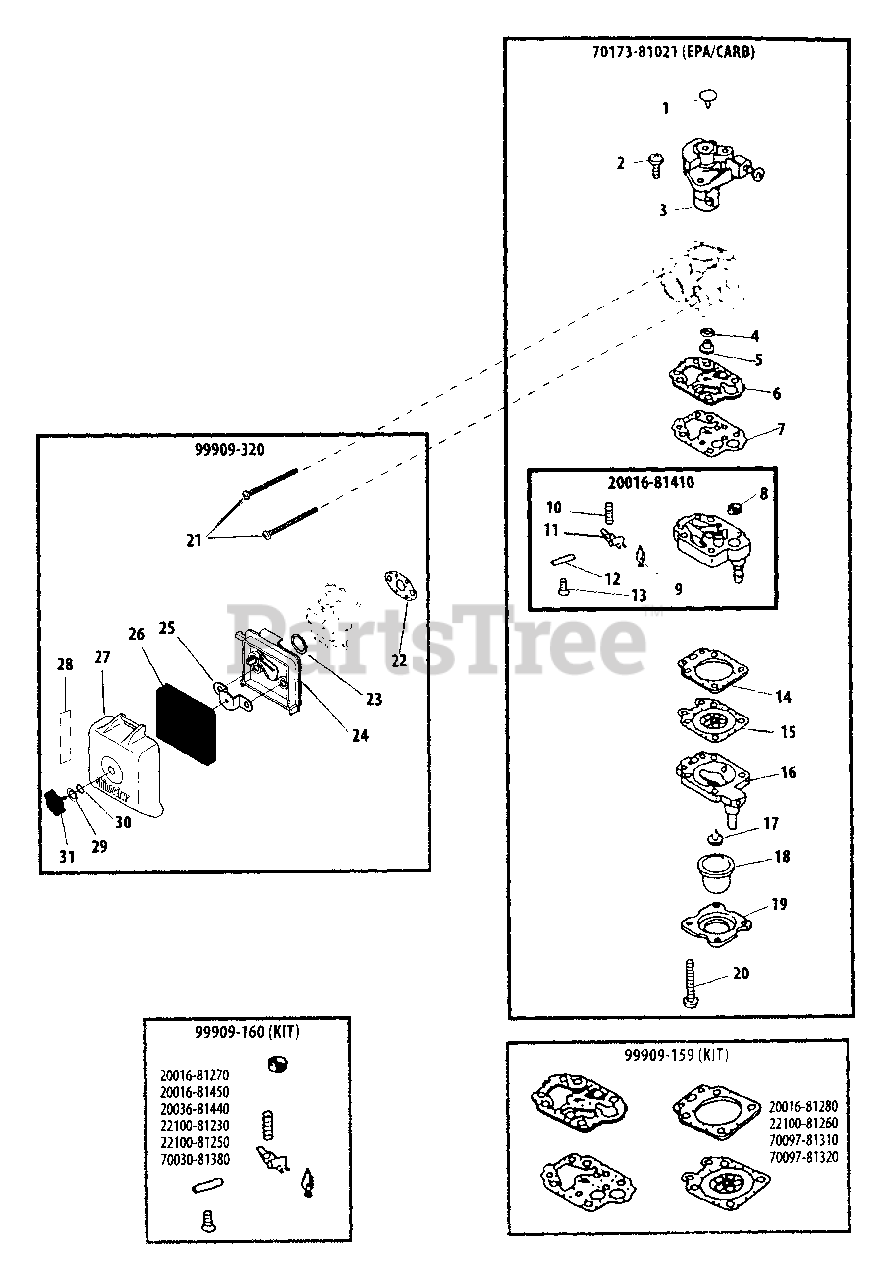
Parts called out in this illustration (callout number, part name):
1	PLUG, WELCH
2	SCREW
3	THROTTLE VALVE ASSY
4	O-RING
5	JET, MAIN - 38
6	GASKET, PUMP
7	DIAPHRAGM, PUMP
8	STRAINER
9	VALVE, INLET NEEDLE
10	SPRING, METERING LEVER
11	LEVER, METERING
12	PIN, METERING LEVER
13	SCREW, METERING LEVER PIN
14	GASKET, METERING
15	DIAPHRAGM, METERING
16	BASE, PURGE
17	VALVE, CHECK
18	BULB, PURGE
19	RETAINER, PURGE BULB
20	SCREW, PUMP COVER
21	SCREW - 5X67
22	GASKET
23	O-RING - 15
24	CASE, AIR FILTER
25	PLATE, PREVENT
26	FILTER, AIR - FOAM
27	COVER, AIR FILTER
28	LABEL - CHOKE
29	WASHER - CONICAL
30	O-RING
31	THUMBSCREW
20016-81410	PUMP BODY ASSY
70173-81021	CARBURETOR
99909-159	DIAPHRAGM/GASKET KIT
99909-160	REPAIR KIT
99909-320	AIR FILTER ASSY
